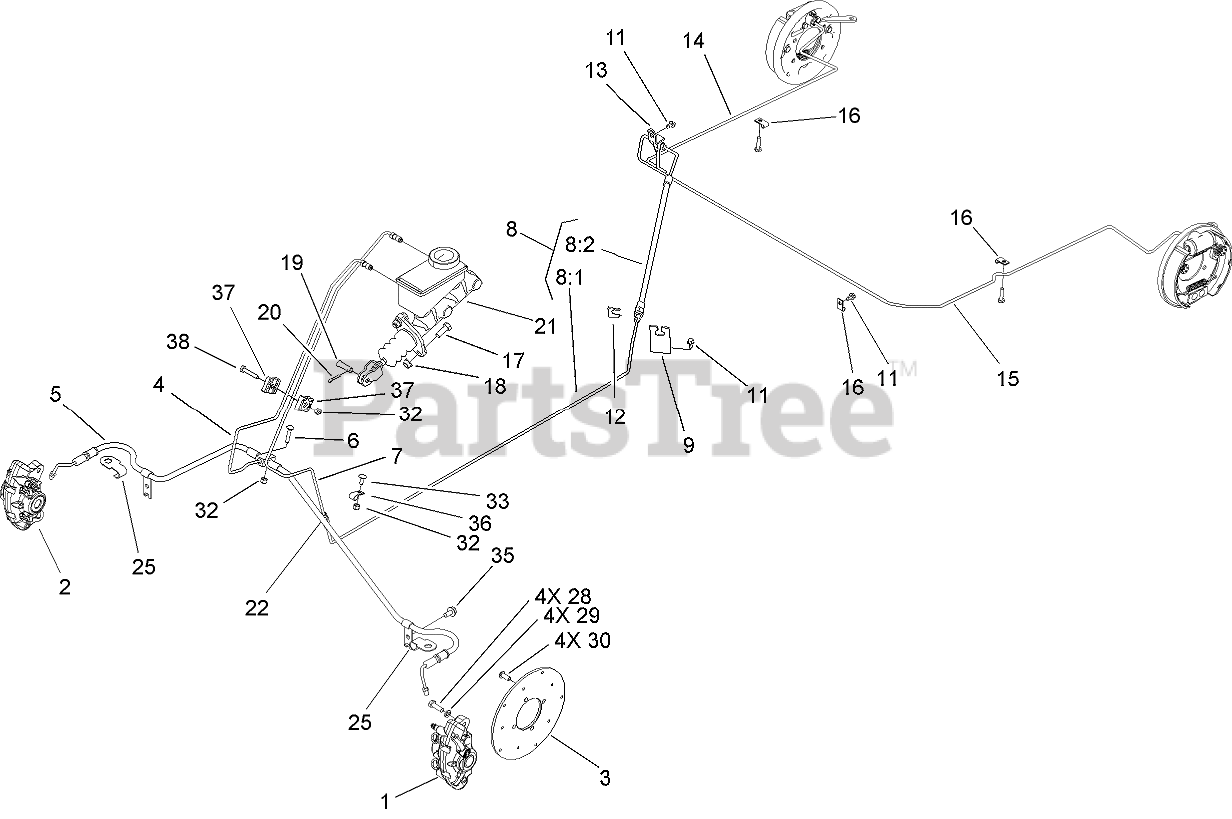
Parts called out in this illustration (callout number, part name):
1	CALIPER-LH
2	CALIPER-RH
4	TUBE-BRAKE, FRONT
5	FRONT HOSE ASM
6	SCREW-CARR
7	TUBE-BRAKE, REAR
8	Complete Rear Brake Hose ASM
8:1	TUBE-BRAKE, REAR
8:2	HOSE-BRAKE, REAR
9	BRACKET-HOSE, BRAKE
11	SCREW
14	TUBE-BRAKE, REAR (RH)
15	TUBE-BRAKE REAR, LH
16	CLIP-CLOSED, INSULATED
17	SCREW-HH
18	NUT-HHF, WHIZ
19	PIN-CLEVIS
20	PIN-COTTER
21	MASTER CYLINDER ASM
22	UNION
25	BRACKET-HOSE
28	SCREW-HH
29	WASHER-LOCK
30	SCREW-HSBH
32	NUT-LOCK, NI
33	SCREW-CARR
35	SCREW-HWHTF
36	CLAMP-R
37	CLAMP-TUBE
38	SCREW-HH
